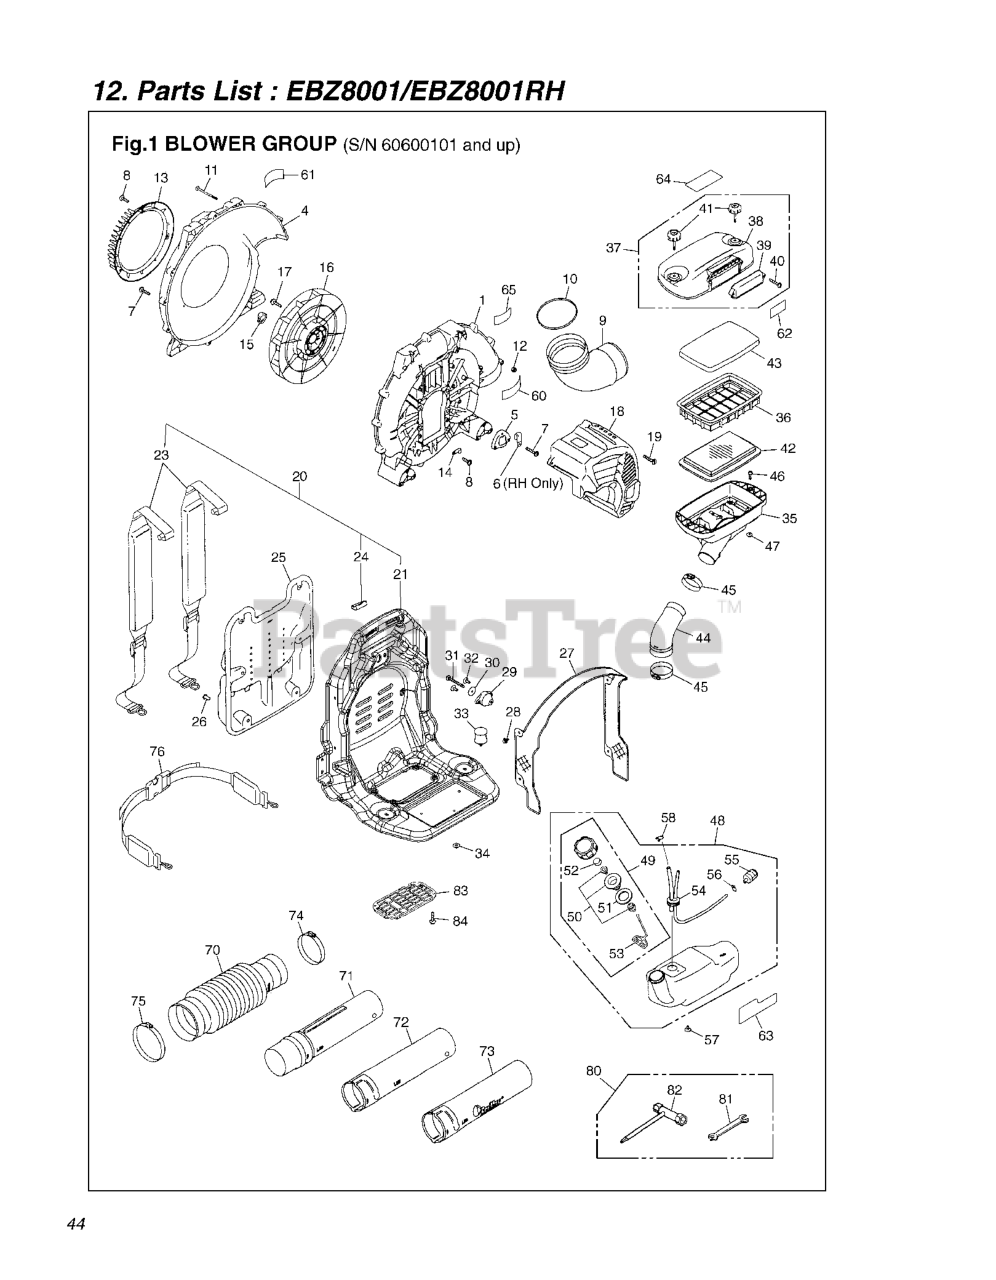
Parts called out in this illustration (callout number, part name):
1	VOLUTE CASE
10	0-RING
13	COVER (FUNNEL)
14	CLAMP
18	COVER.ENGINE
20	FRAME USE 848L5M3502
21	FRAME EBZ8001(R-848L583513,14)
24	CLIP
25	PAD
26	CLIP
28	CLIP
29	DAMPER UPPER
30	WASHER
31	BOLT
33	DAMPER
37	COVER ASSY
41	KNOB BOLT-RED
42	ELEMENT
43	ELEMENT
45	CLAMP
48	TANK-A***
49	CAP A
50	HOLDER-A
54	PIPE C
55	FILTER ASSY
56	CLIP
58	CLIP
60	LABEL.CAUTION
61	LABEL, NET
62	LABEL EBZ8001
63	LABEL,TANK
70	HOSE ALT 848L6565A0
71	SWIVEL JOINT
74	CLAMP
75	CLAMP
76	BAND ASSY (RPLS 848L583620)
80	TOOL-SET
82	SOCKET
